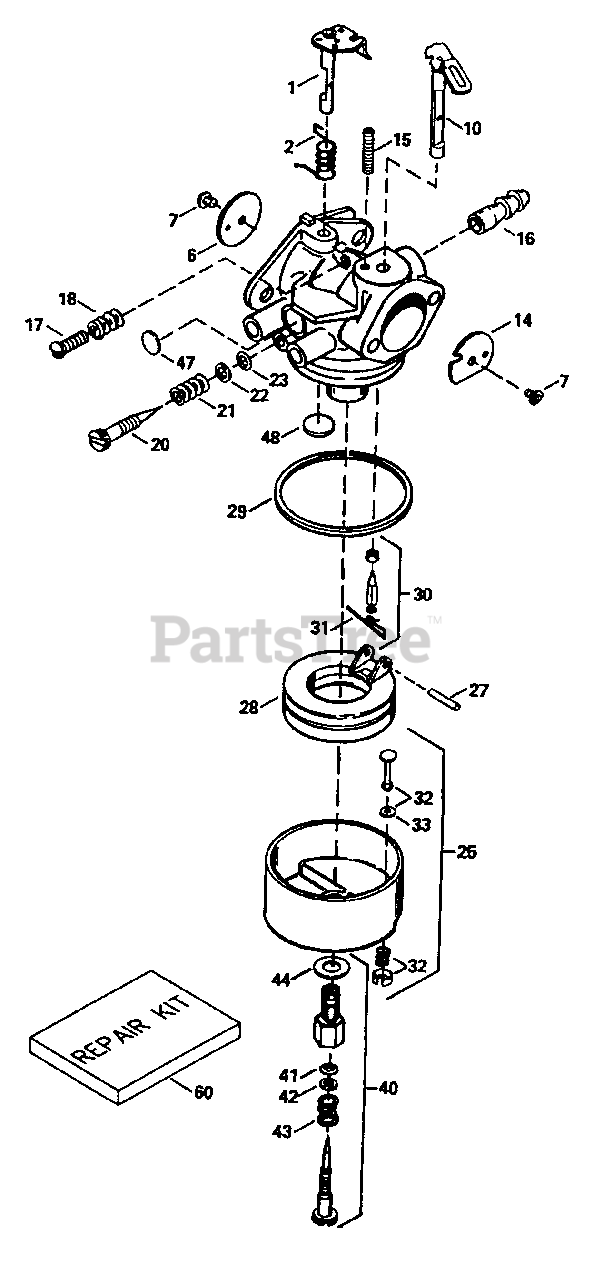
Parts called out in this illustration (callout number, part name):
1	Throttle Shaft 8 Lever Ass'y.
2	Throttle Return Spring
6	Throttle Shutter
7	Throttle & Choke Shutter Screw
10	Choke Shaft & Lever Ass'y.
14	Choke Shutter
15	Choke Positioning Spring
16	Fuel Fitting
17	Idle Speed Screw
18	Tension Spring
20	Idle Mixture Screw
21	Idle Tension Spring
22	Washer, Idle Screw
23	O-Ring, Idle Screw
25	Float Bowl Ass'y.
27	Shaft, Float
28	Float
29	O-Ring, Float Bowl to Body
30	Inlet Needle, Seat & Clip
31	Spring Clip
32	Bowl Drain Ass'y.
33	Drain Plunger Gasket
40	Main Adj. Screw Ass'y.
41	O-Ring, High Speed Mixture Screw
42	Washer, High Speed Mixture Screw
43	Tension Spring, High Speed Mixture Screw
44	Bowl Nut Washer
47	Welch Plug, Idle Mixture Well
48	Welch Plug, Atmospheric Vent
60	Repair Kit
